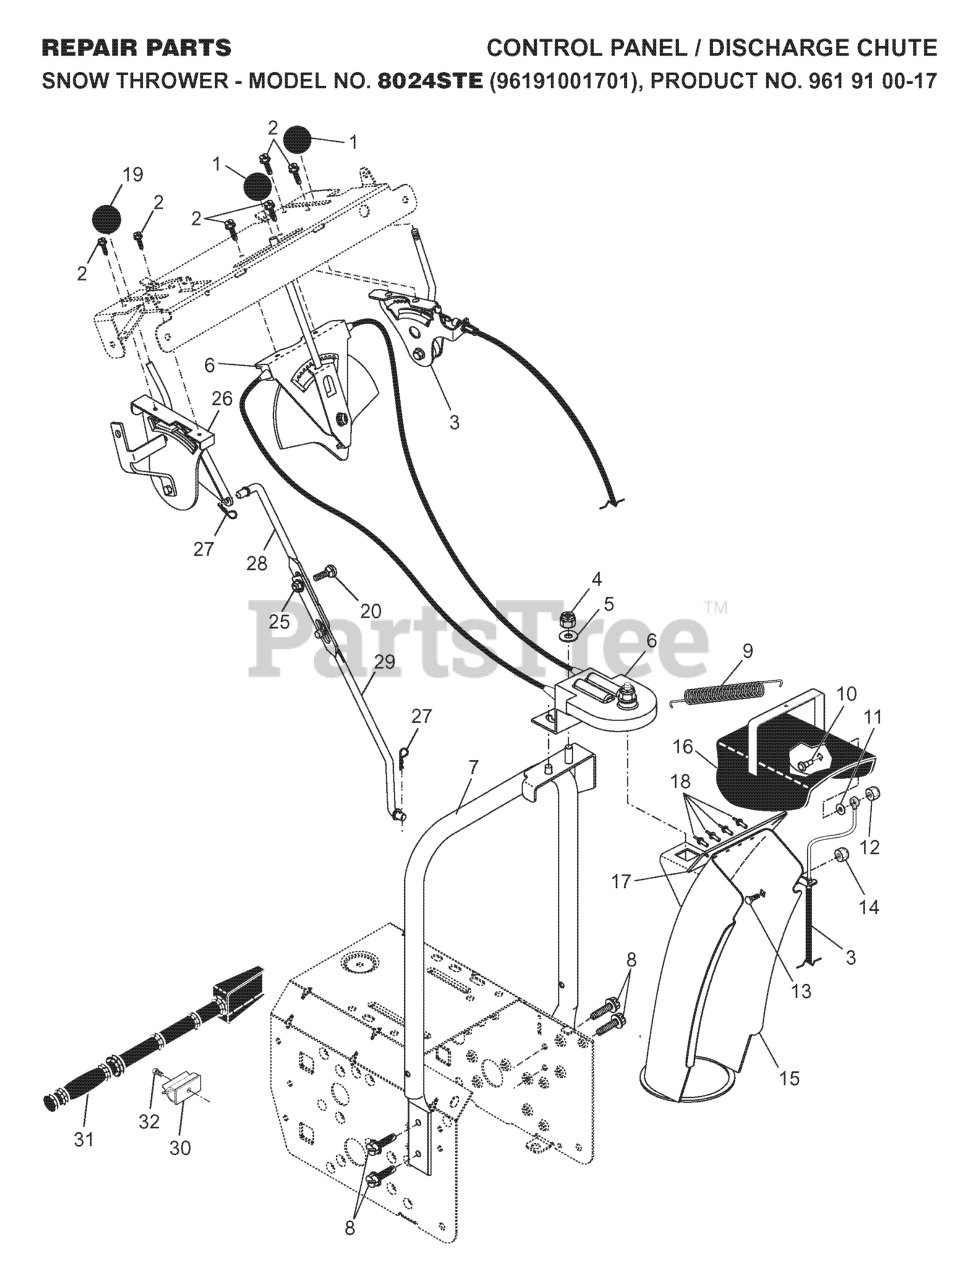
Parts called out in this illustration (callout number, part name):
1	KNOB LEVER, BLACK
2	SCREW #10-24 X 5/8
3	CONTROL.CABLE.DEFLECTOR
4	NUT
5	WASHER
6	CONTROL ASSEMBLY,CHUTE ROTATER
7	SUPPORT, PIVOT
8	SELF-TAPPING SCREW 5/16-18X3/4
9	SPRING.DEFLECTOR.REM.CHUTE
10	BOLT, SHOULDER
11	WASHER, NYLON FRICTION
12	NUT.HEX.FLANGE.1/4
13	BOLT
14	NUT.LOCK.5/16-18
15	CHUTE ASSEMBLY
16	DEFLECTOR.WELDMENT.PNT.ORANGE
17	SEAL, DEFLECTOR
18	RIVET BLIND
19	RED KNOB SHIFTER
20	BOLT
25	NUT.FLANGE.5/16
26	HEAD ASSY SPEED
27	SPRING RETAINER
28	ROD, UPPER SPEED CONTROL
29	ROD, LOWER SPEED CONTROL.SNOW
30	CLIP.CLEANOUT.TOOL
31	CLEAN OUT TOOL
32	SCREW.HWH.13-16-5.8.BZP
